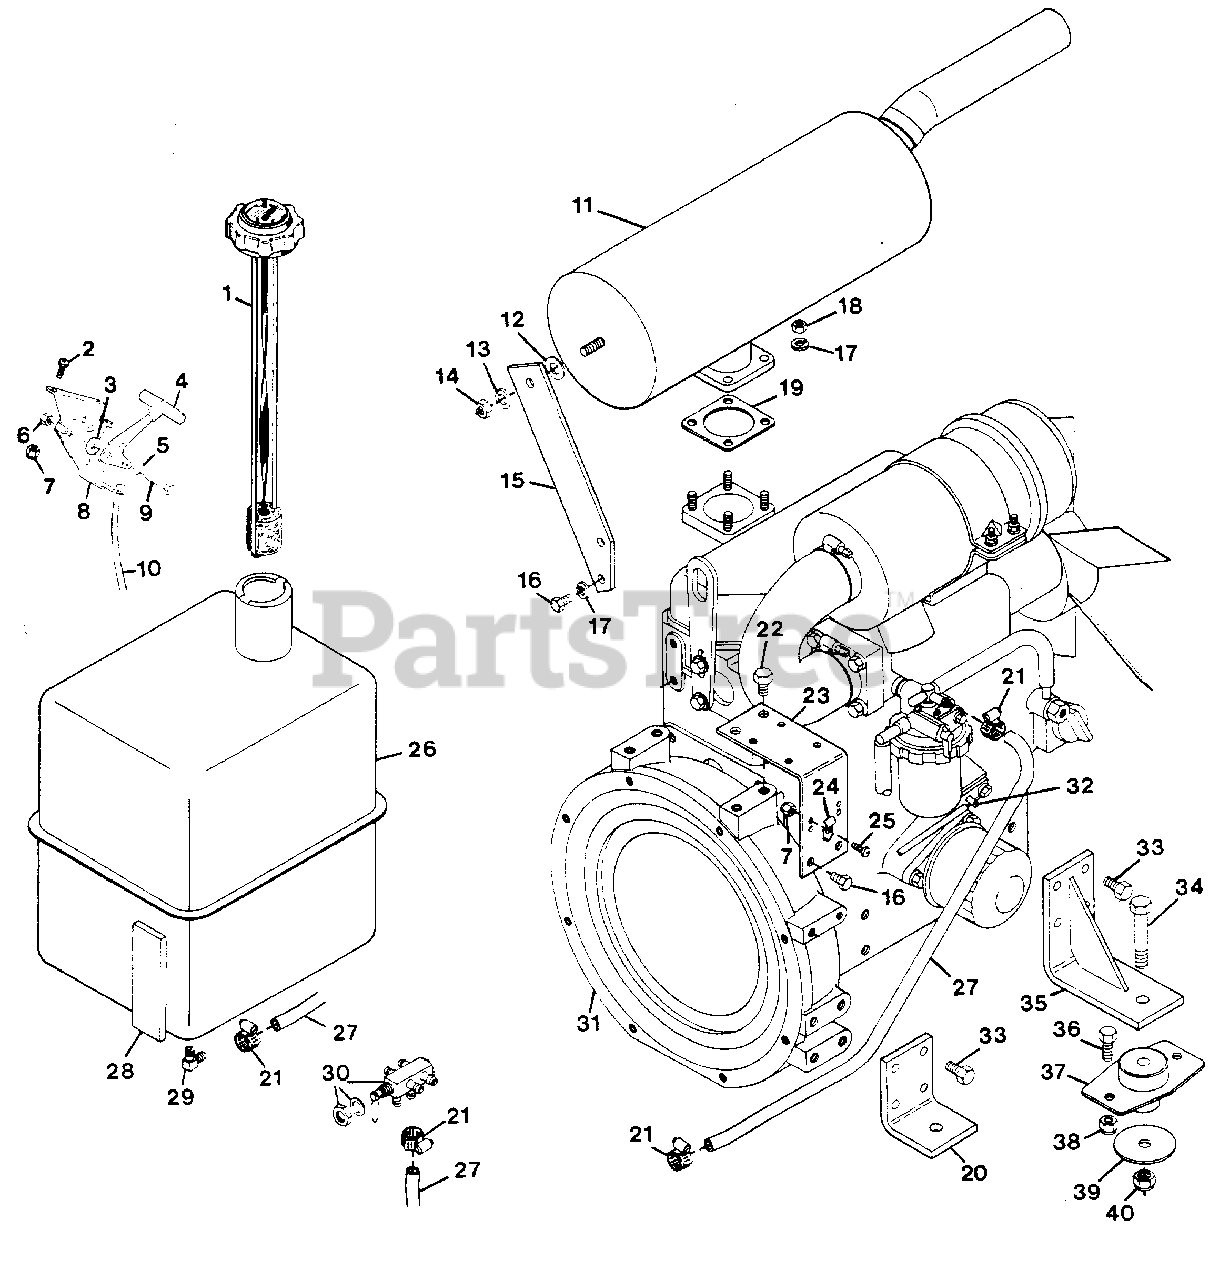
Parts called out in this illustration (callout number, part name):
1	Gauge, Fuel
2	Screw, Machine 10-24x.50 PHD
3	Washer, Friction
4	Assembly, Knob and Lever
5	Washer, Spring
6	Nut, Lock 1/4-28
7	Nut, Lock 10-24
8	Bracket, Mounting L.H.
9	Bolt, Hex 1/4-28x.75
10	Assembly, Conduit
11	Muffler, Yanmar
12	Washer, Flat .406x.812x.065
13	Washer, Lock 3/8 Reg.
14	Nut, Hex 3/8-16
15	Brace, Muffler
16	Bolt, Hex M8 x 1.25 16mm
17	Washer, Lock 5/16 Reg.
18	Nut, Hex M8 x 1.25
19	Gasket, Exhaust
20	Mount, Engine
21	Clamp, Hose
22	Bolt, Hex M10 x 1.5 16mm
23	Bracket, Control
24	Clip
25	Screw, Machine 10-24x.625 PHD
26	Tank, Fuel
27	Fuel Line .5 OD x .25 ID,
28	Pad, Gas Tank
29	Elbow, Hose
30	Valve, Fuel Control
31	Engine, Yanmar
32	Clamp, Swivel Wire
33	Bolt, Hex M10 x 1.5 20mm
34	Bolt, Hex 1/2-13x2.75
35	Weldment, Engine Mount
36	Bolt, Hex 3/8-16x1.00
37	Mount, Engine
38	Nut, Lock 3/8-16
39	Washer, Snubbing
40	Nut, Lock 1/2-13
